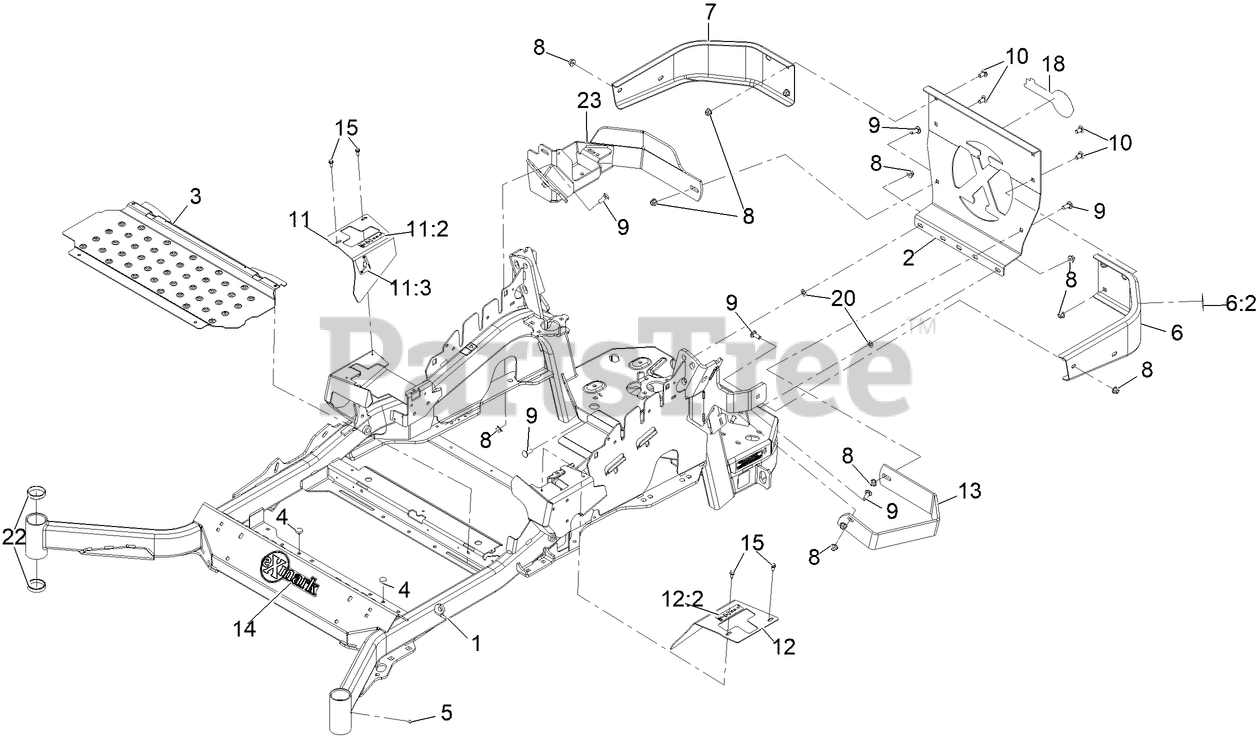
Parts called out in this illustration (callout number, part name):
1	MAINFRAME SERVICE ASM - 72
2	PLATE,REAR GUARD
6	LH BUMPER ASM
6:2	DECAL-WARNING
7	BUMPER-RH
8	NUT-HF, NI
9	SCREW-CARR
10	SCREW-CARR
11	RH MOTION CONTROL COVER ASM
11:2	DECAL-CONTROL, MOTION
11:3	DECAL-PARK BRAKE, CE
12	LH MOTION CONTROL COVER ASM
12:2	DECAL-CONTROL, MOTION
13	GUARD-MUFFLER
14	DECAL-EXMARK
15	SCREW-HWH
18	DECAL, EXMARK LOGO
20	NUT-PUSH
22	CUP-BEARING
23	BATTERY GUARD ASM
